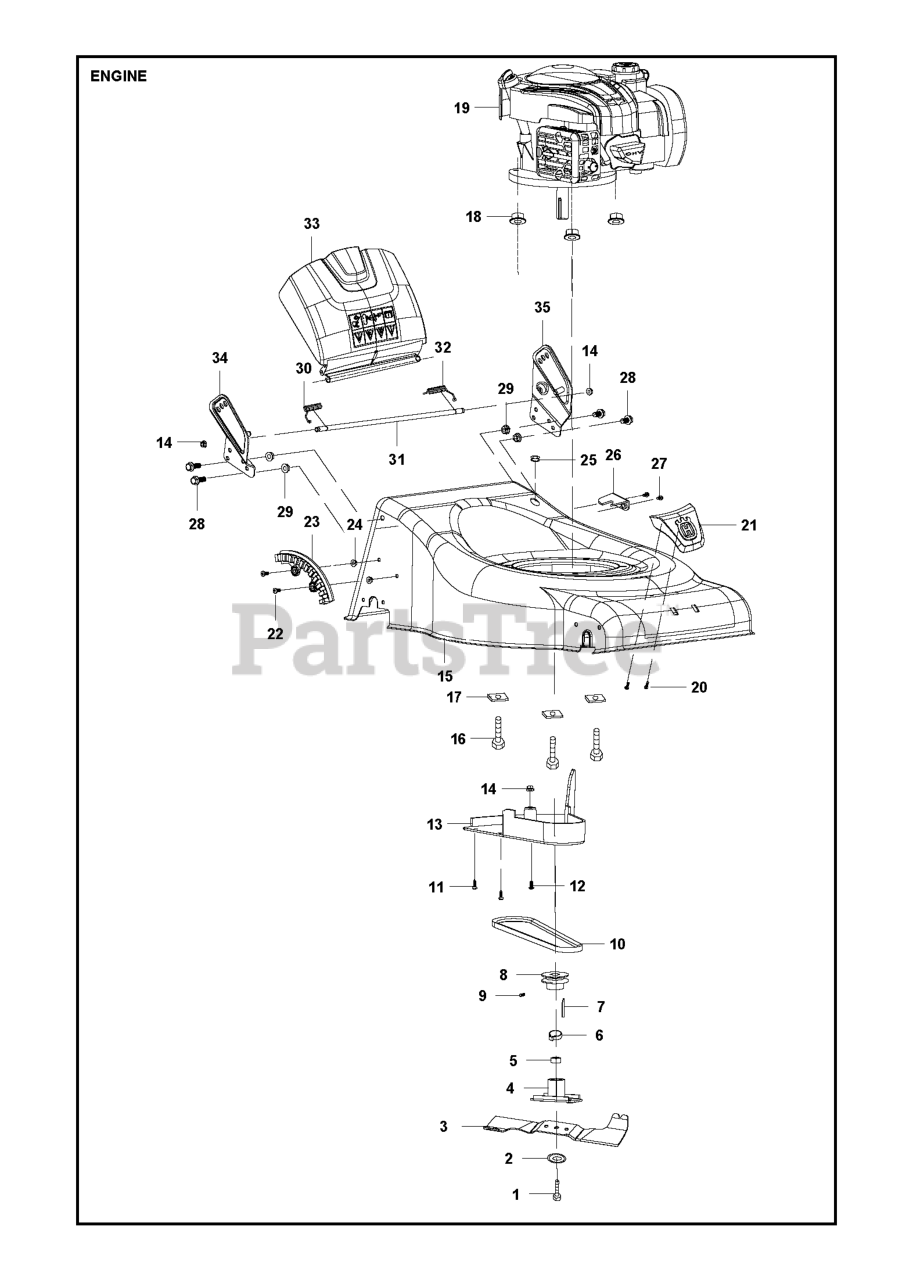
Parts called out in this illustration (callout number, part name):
12	SCREW M6*16 #26800204601
14	LOCK NUT M6,GB/T6187.1-2000 #2
18	LOCKING BOLT M8,GB6187.1 #2680
23	SEGMENT #25214200102
25	COVER #25217800104
27	BOLT M6*12,(GB5787-86)GB6674.1
28	BOLT M8*16 #26800606401
30	SPRING #26801125501
32	BRACKET #26801125401
